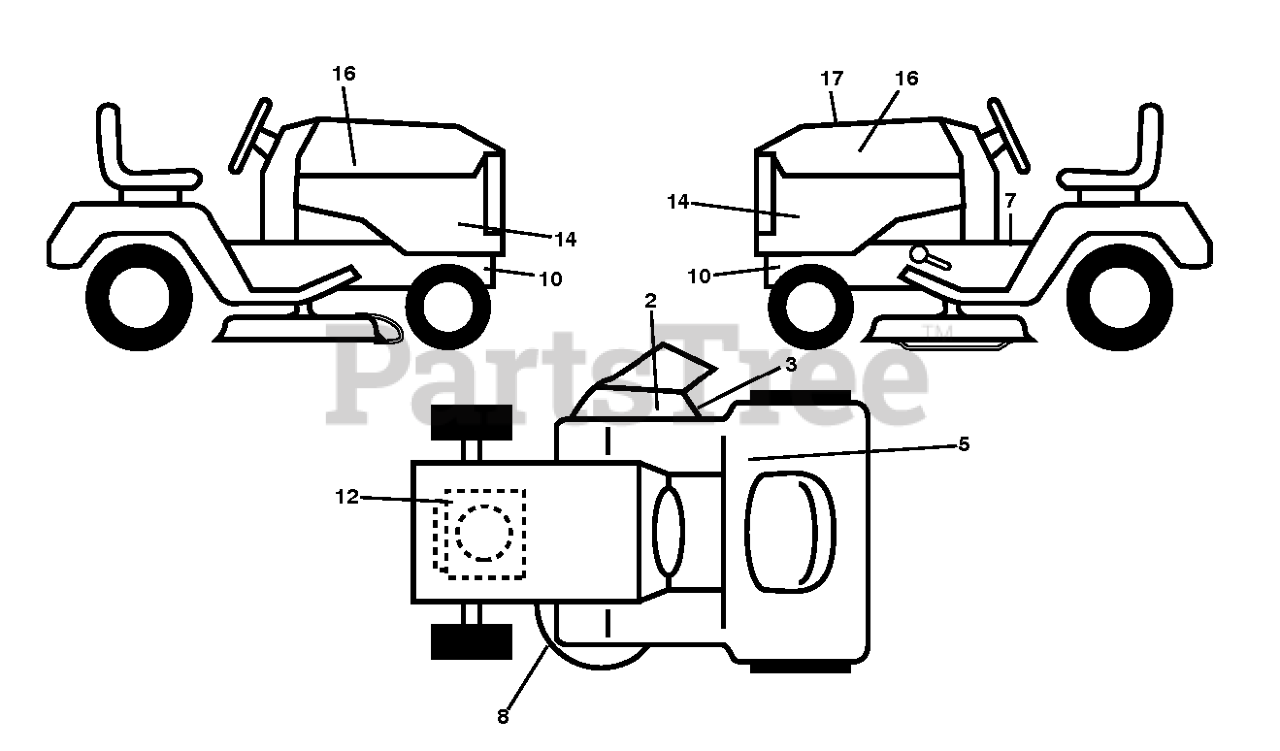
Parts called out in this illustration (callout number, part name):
2	DECAL, DECK DEFLECTOR, WARNING
3	DECAL.DFLCTR.WARNNG.CTFNGR.SYM
7	DECAL.TRACTOR.SADDLE
8	DECAL.V-BELT.SCH.42/46"MEC/ELE
10	DECAL.CHASSIS.HOT.MUFFLER
12	DECAL.ENGINE.WARNING
14	DECAL.SDPNL.HUSQGT.TS242.RH/LH
16	DECAL.WB.178MM.15.HUSQ.NEWBRAN
17	DECAL.RPL.KW.FR.TLW.42E.K46
